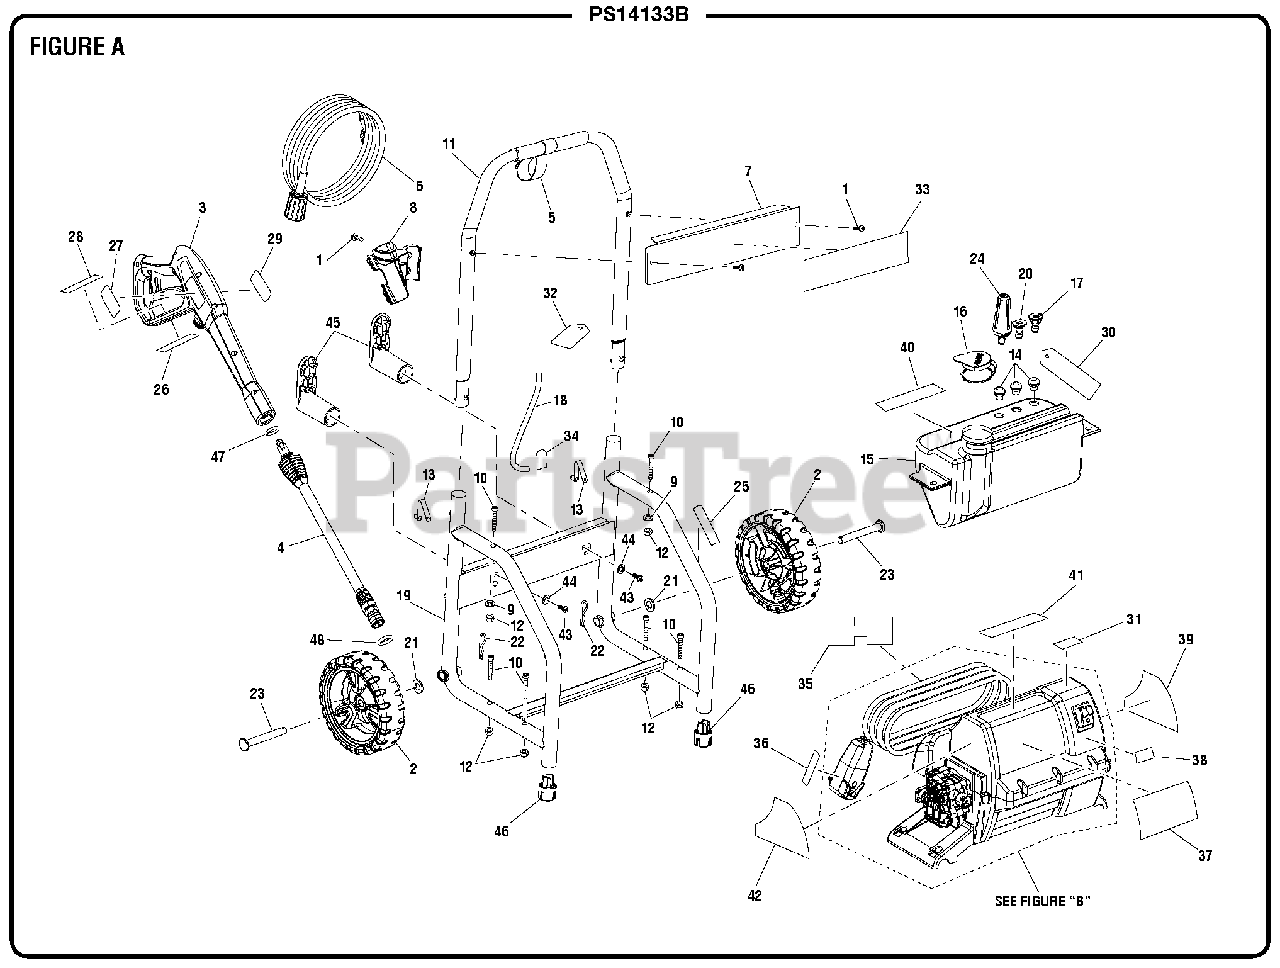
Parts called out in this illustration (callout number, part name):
1	Bolt (M6 x 20 mm, Pan Hd.)
2	Wheel Assembly
3	Trigger Handle
4	Spray Wand
5	Hook and Loop Strap
6	High Pressure Hose (20 ft)
7	Performance Panel
8	Trigger Handle Holder
9	Washer (OD18 x ID6.5 x 1.5t)
10	Bolt (M6 x 40 mm)
11	Handle Assembly
11	Inquiries Label
12	Lock Nut (M6)
13	Spring Clip
15	Soap Tank Assembly
16	Soap Tank Cap
17	Soap Nozzle
18	Chemical Siphon Tube
19	Frame Assembly
20	15deg Nozzle
21	Washer (OD24 x ID12.5 x 2.5t)
22	Cotter Pin
23	Axle (M12 x 67 mm)
24	Turbo Nozzle
26	Trigger Handle Rating Label
27	Logo Label (Trigger Handle)
28	Warning Label (Trigger Handle)
29	Trigger Handle Warning Label (Eng)
30	Warning Hangtag
31	Soap Dilution Label
32	Nozzle Hangtag
33	Performance Label
34	Power Cord Unlock Label
35	Cord Wrap Warning Label
36	GFCI Label
37	Logo Label
38	On/Off Label
39	Danger Icon Label
40	Quick Start Label
41	Nozzle Selection Label
42	Regulatory Danger Label
43	Screw (M4.8 x 19 mm, Round Hd.)
44	Washer (OD12 x ID6.6 x 1.6t)
45	Cord Wrap Arm
47	O-Ring (ID8 x 2t)
48	O-Ring (ID9.5 x 2.6t)
